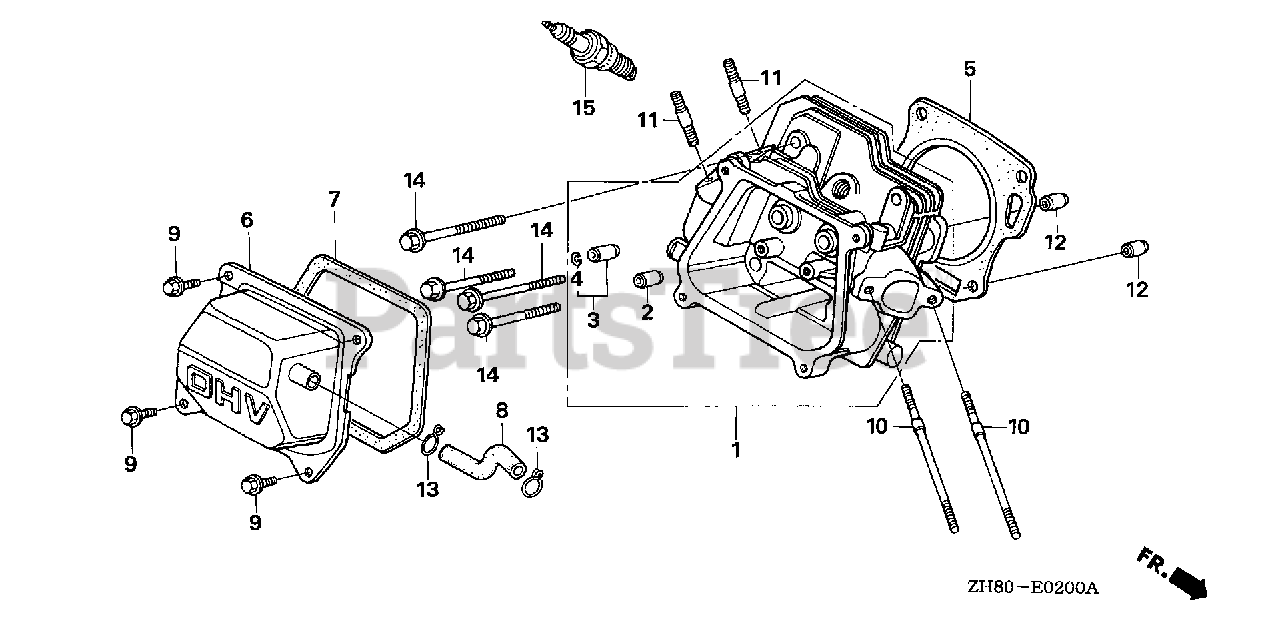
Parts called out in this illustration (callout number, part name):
1	CYLINDER HEAD
2	GUIDE, VALVE (OVER SIZE)
3	GUIDE, EX. VALVE (OVER SIZE)
4	CLIP, VALVE GUIDE
5	GASKET, CYLINDER HEAD
6	COVER, HEAD
7	GASKET, HEAD COVER
8	TUBE, BREATHER
9	BOLT, FLANGE (6X13) (CT200)
10	BOLT, STUD (6X112)
11	BOLT, STUD (8X32)
12	PIN, DOWEL (10X16)
14	BOLT, FLANGE (8X60)
15	SPARK PLUG (BPR5ES) (NGK)
15	SPARK PLUG (W16EPR-U) (DENSO)
15	SPARK PLUG (BPR6ES) (NGK)
15	SPARK PLUG (W20EPR-U) (DENSO)
